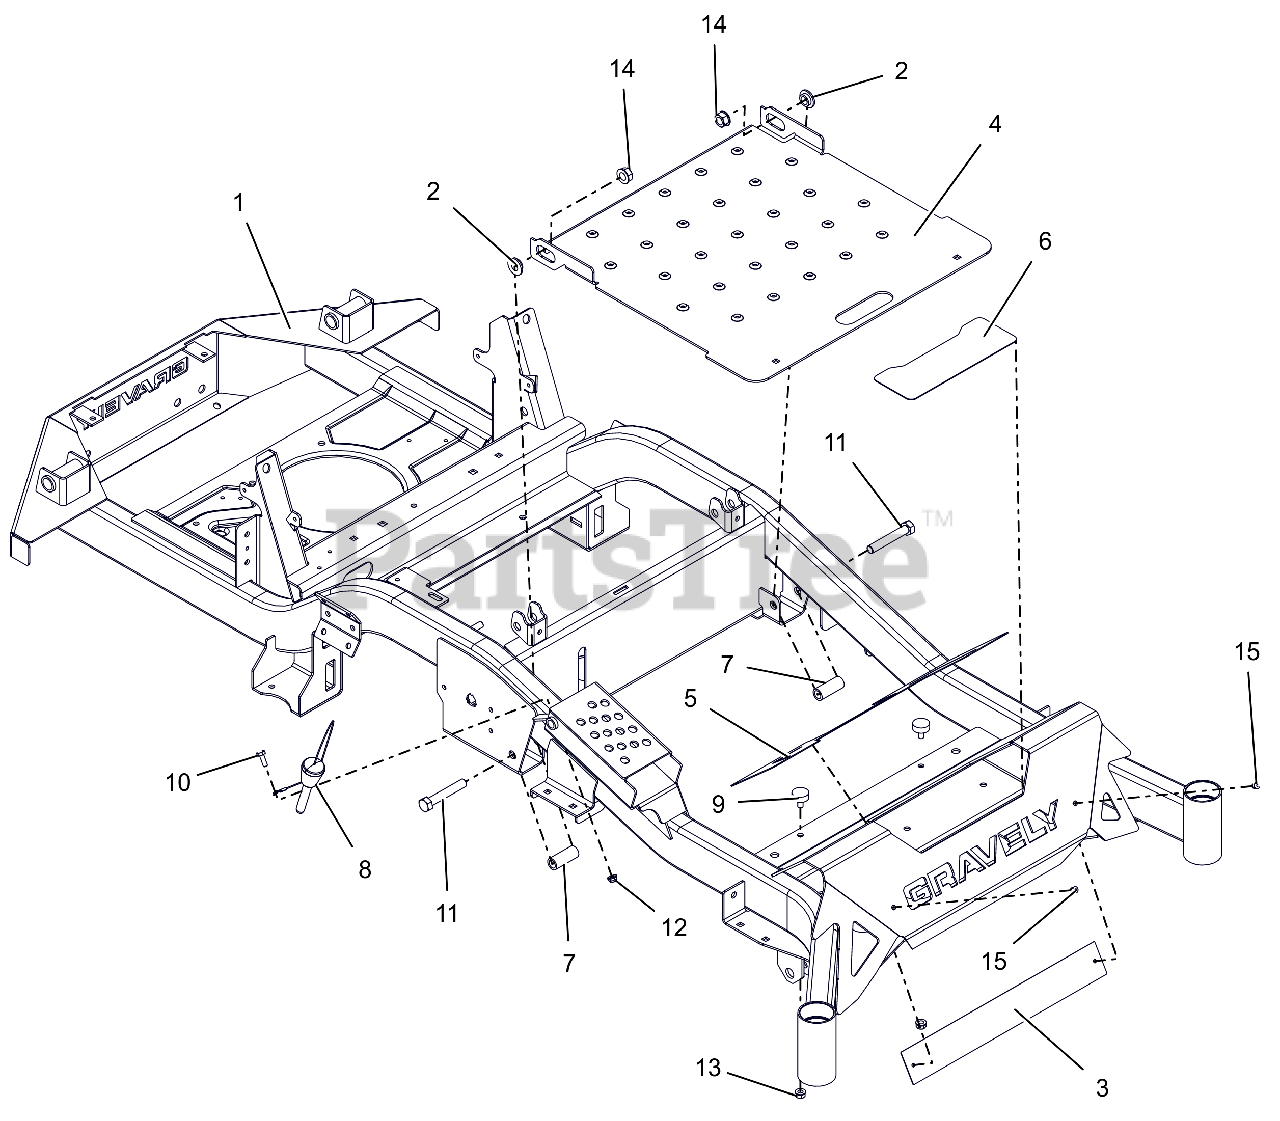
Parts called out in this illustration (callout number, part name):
1	HD 44-52 FRAME W/SAFETY DECALS
2	BSHG-FLG .515X.750X.310X1.120
3	PLATE, BACK FOOT-REST XL
4	KIT,ACCESS PANEL W/DECALS-RED
5	GRIP, FRONT
6	GRIP, STEP
7	SPACER, .515X.75X1.83
8	PIN, MAGNETIC .50X2.50
9	BUMPER, RUBBER
10	BLT, HEX .25-20X.75 G5 ZCC
11	BLT, HEX .50-13X3.00 G5 ZCC
12	NUT,NYL-FLG .25-20 GF ZCC
13	NUT,SPNLK-FLG .31-18 G5 ZCC
14	NUT-LK-TOP-FLG .500-13 GF ZCC
15	RIVET, .1875 AL/AL .126-.250
